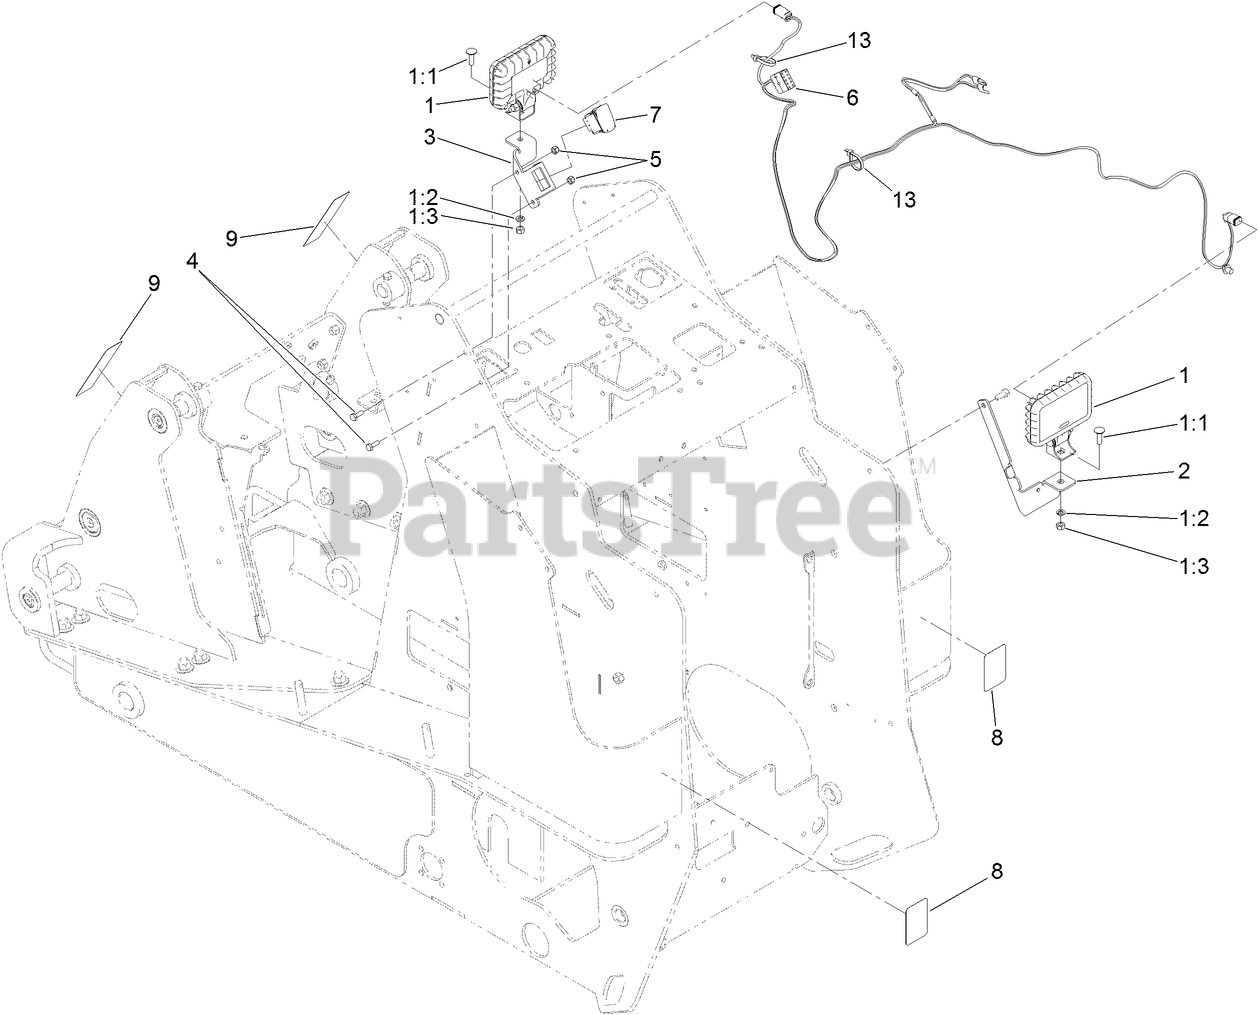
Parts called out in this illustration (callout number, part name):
1	LIGHT-WORK, LED
1:1	SCREW-CARR
1:2	WASHER-LOCK
1:3	NUT-HEX
2	BRACKET-LIGHT, LH
3	BRACKET-LIGHT, RH
4	SCREW-HH
5	NUT-LOCK, NI
6	HARNESS-WIRE
7	SWITCH
8	REFLECTOR
9	TAPE-REFLECTIVE
13	TIE-CABLE
